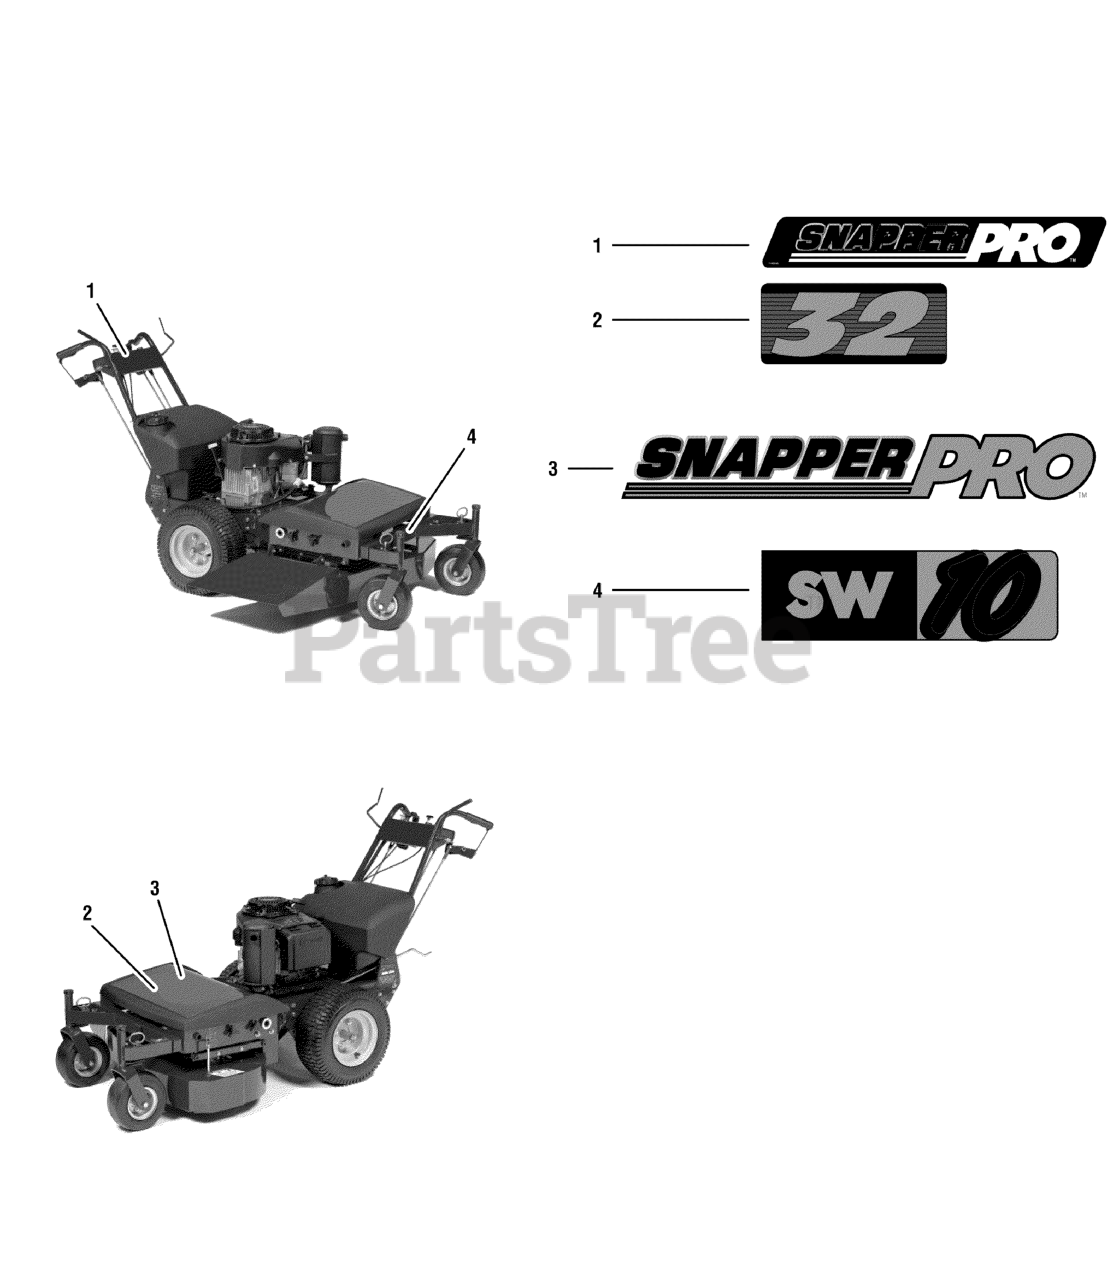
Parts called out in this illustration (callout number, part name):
1	DECAL, SNAPPER PRO
2	DECAL, 32" SILVER COMMERCIAL
3	DECAL, SNAPPER PRO, HEAT
4	DECAL, SW10
